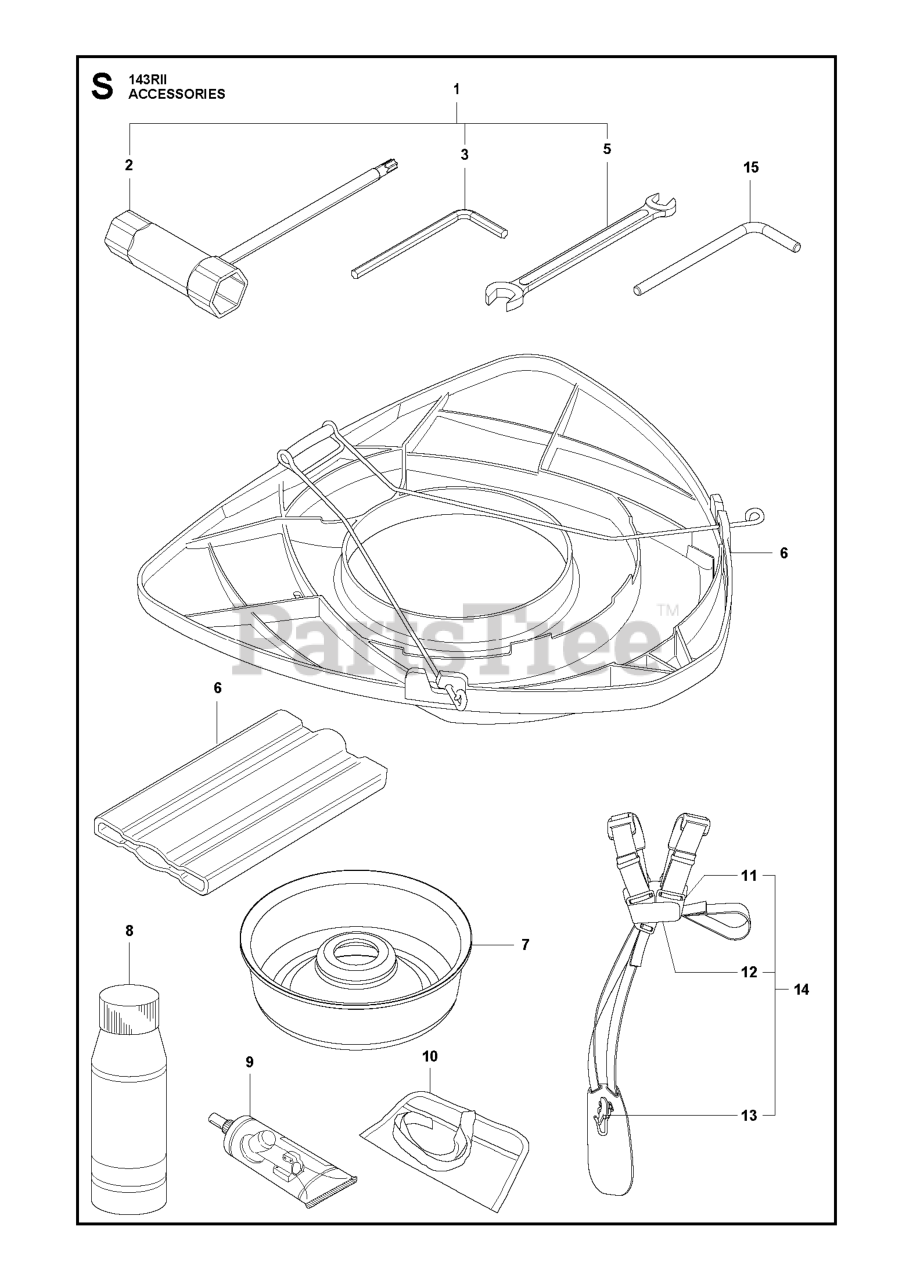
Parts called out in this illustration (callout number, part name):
5	WRENCH SPANNER
6	BAR GUARD
6	TRANSPORT GUARD
7	SUPPORT CUP
8	Air Filter Oil 1l.
9	BEVEL GEAR GREASE
13	HOOK, CPL.
14	HARNESS DUO
